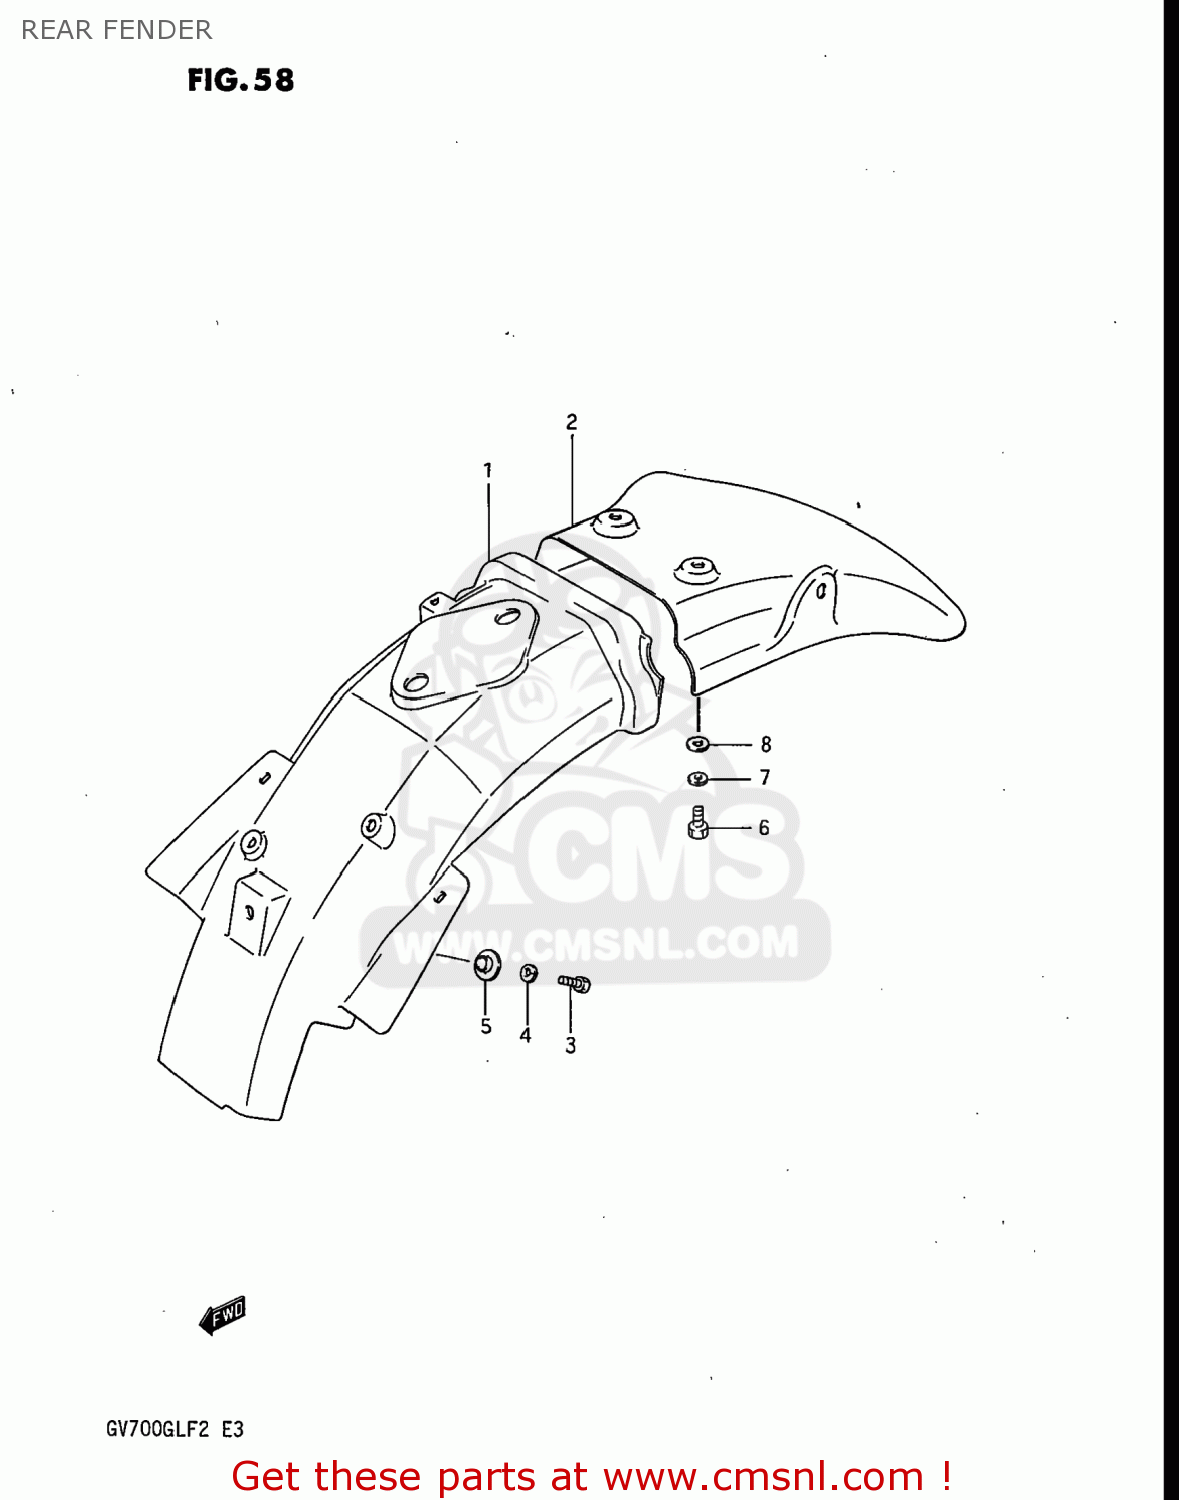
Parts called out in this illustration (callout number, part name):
1	BODY,REAR FENDER,FRONT
2	BODY,REAR FENDER,REAR
3	BOLT
4	WASHER,LOCK
5	WASHER
6	BOLT
7	WASHER,LOCK
8	WASHER, LOWER
